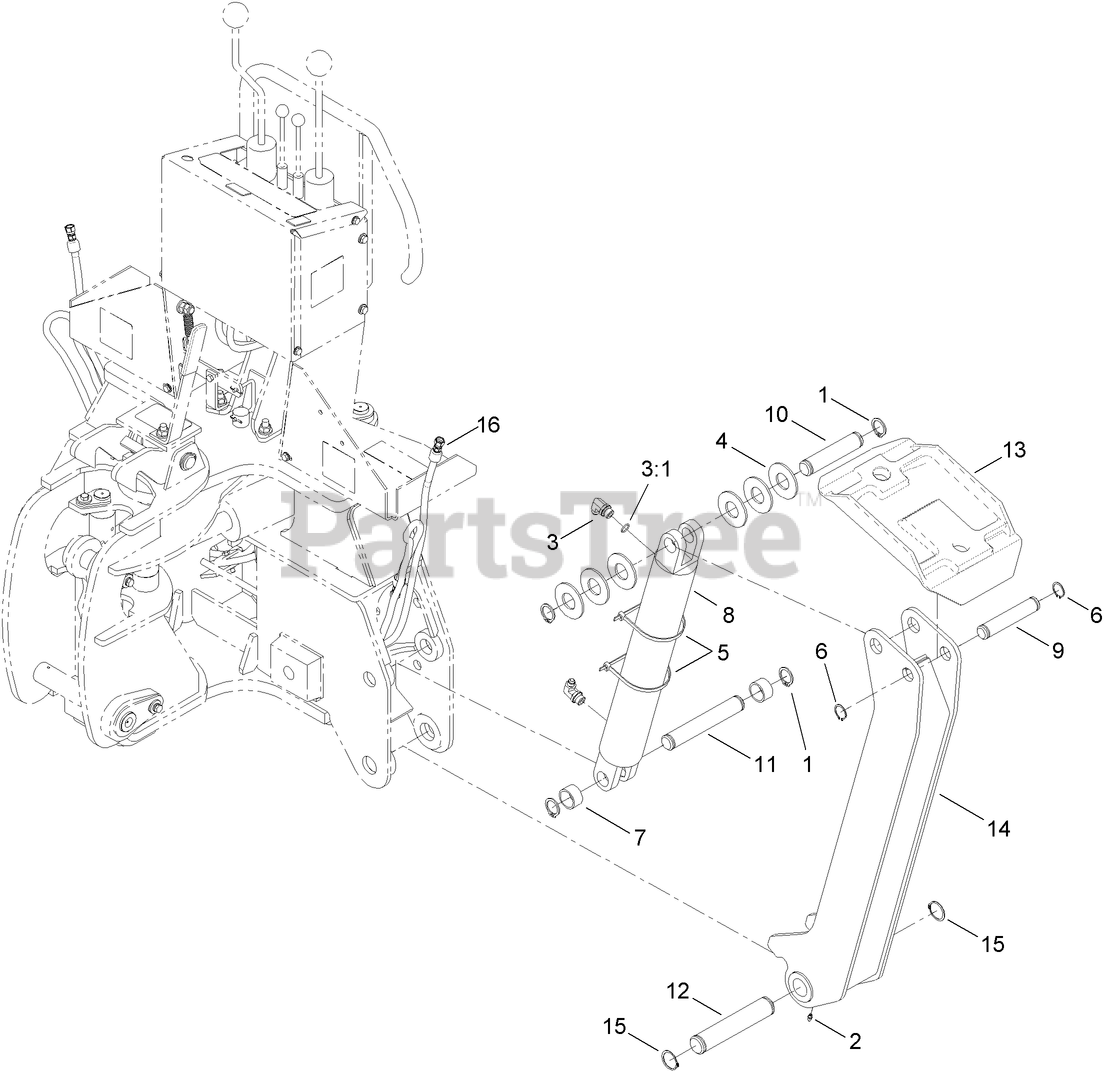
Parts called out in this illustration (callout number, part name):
1	RING-RETAINING, EXTERNAL
2	FITTING-GREASE
3	FITTING-ELBOW, 90 DEG
3:1	O-RING
4	WASHER-FLAT (HARDENED)
5	TIE-CABLE
6	Ring-Retaining
7	BUSHING
8	HYD CYLINDER ASM
9	PIN (STABILIZER PAD END)
10	PIN-STABILIZER (CYLINDER ROD END)
11	PIN-STABILIZER CYLINDER TO ARM
12	PIN-Stabilizer Arm
13	PAD-STABILIZER
14	STABILIZER
15	RING-RETAINING, EXTERNAL
16	HOSE ASM
